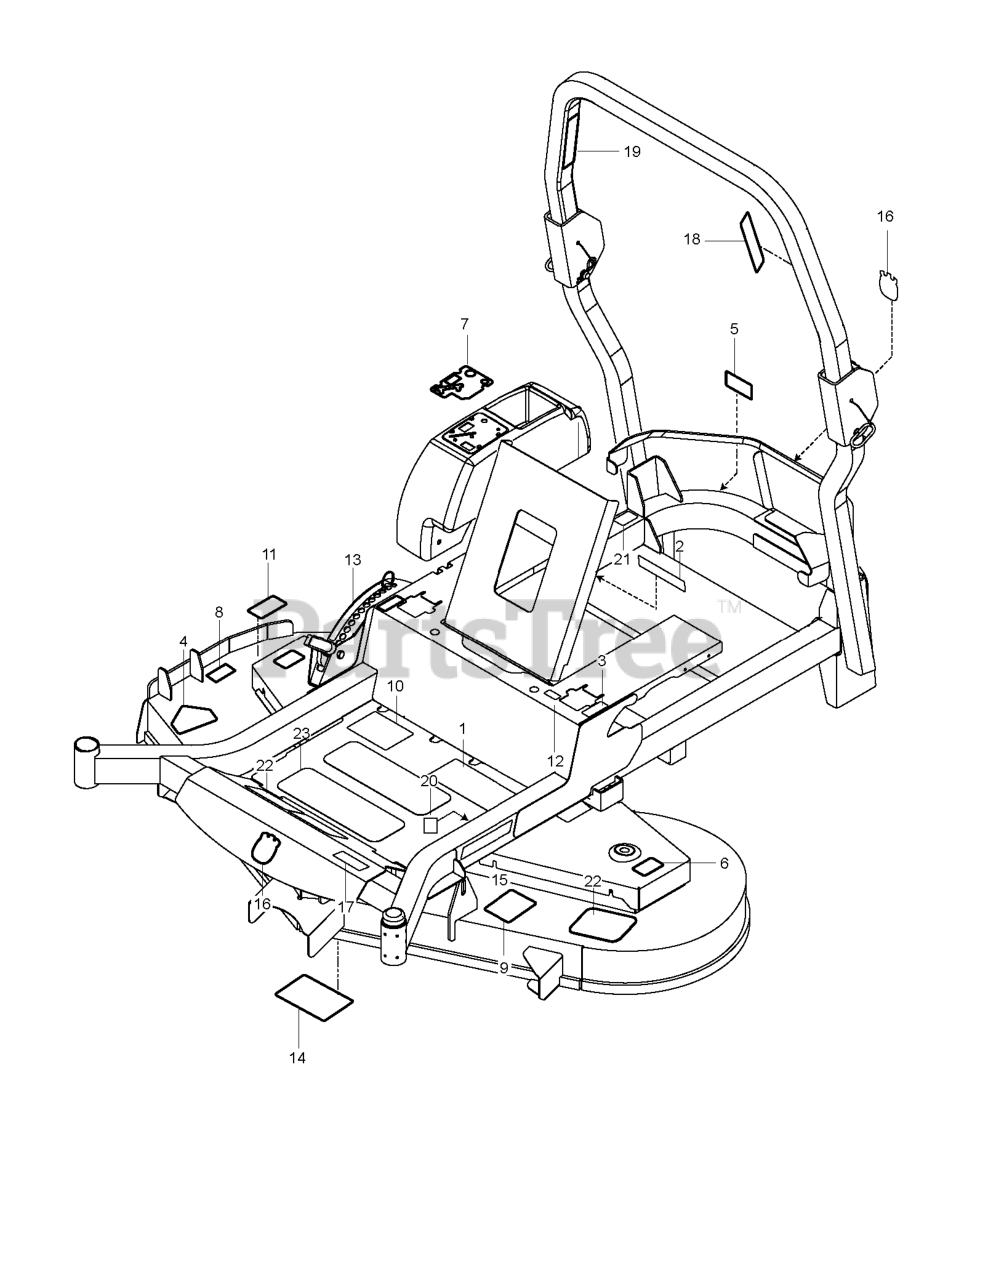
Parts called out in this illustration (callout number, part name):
1	DECAL, WARNING
2	EURO DECAL-BATTERY WARNIN6
3	DECAL, MOTION CONTROL
4	DECAL, DECK DEFLECTOR, WARNING
5	DECAL, BELT DRIVE
6	DECAL.DECK.6MIL.EURO.NOSTEP
7	DECAL, CONSOLE HUS
8	DECAL, EURO SEVERING
9	DECAL, BELT ROUTING
10	DECAL.ZTR.STRTNGINST.REMOTECHK
11	DECAL.DECK.6MIL./DEF.SHLD.WARN
12	DECAL, F.S.T.
13	DECAL, HEIGHT ADJUST
14	DECAL, SERVICE
15	RP.DECAL.BADGE.170MM.TEXTLOGO
16	DECAL.AUGER.HUSQ.CROWN.SNOW
17	DECAL ZTR MZT61 HUSQVARNA
18	DECAL ROPS
19	DECAL, ROPS, WARNING
20	DECAL.80.DBA.AUSTRALIA
21	DECAL, ECM, AUSTRALIA
22	ANTI-SKID PAD
